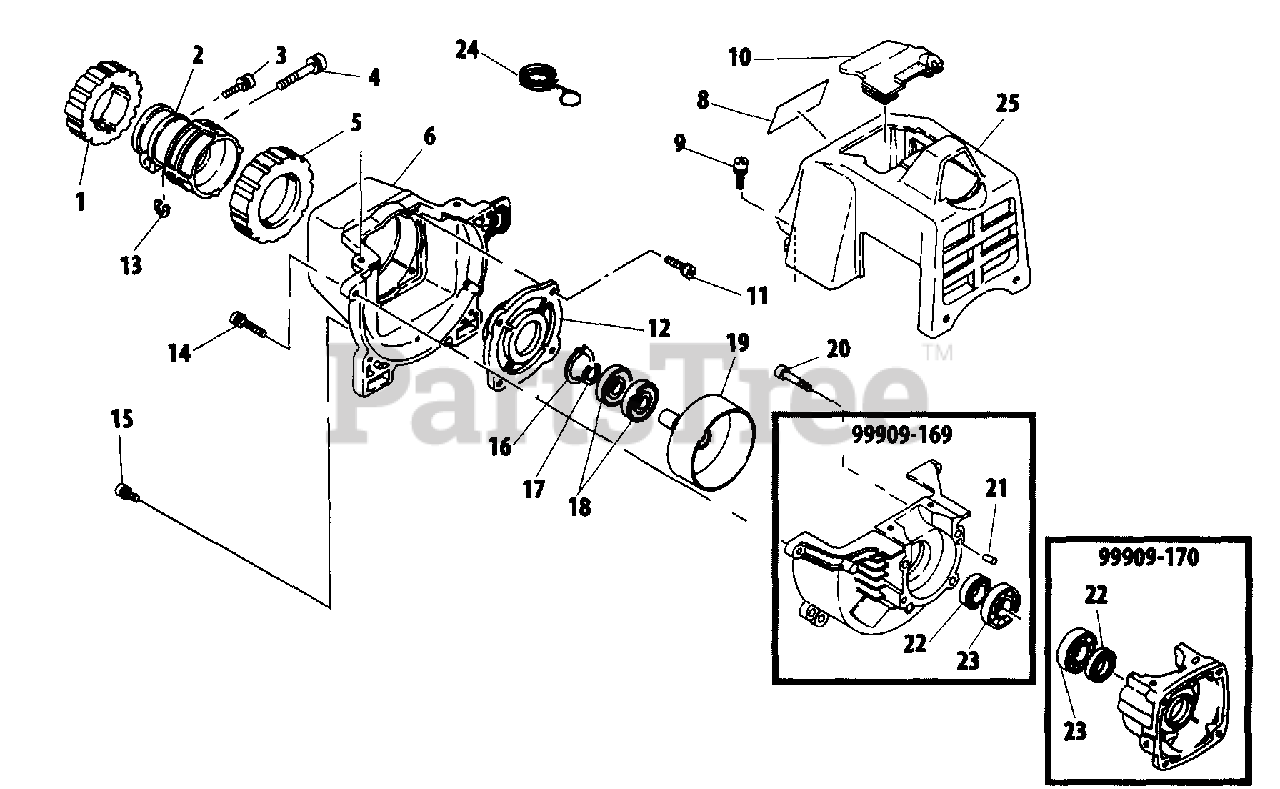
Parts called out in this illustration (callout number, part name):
1	CUSHION - FRONT
2	JOINT
3	SCREW - 5X65
4	SCREW - 6X28
5	CUSHION - REAR
6	CASE, FAN
8	LABEL - MODEL
9	SCREW - 5X16
10	COVER
11	SCREW - 5X16
12	CASE, CLUTCH
13	SHIM
14	SCREW - 5X18
15	SCREW - 5X20
16	RING, RETAINING - 28
17	RING, RETAINING
18	BEARING, BALL - 6001DDUC3
19	DRUM, CLUTCH
20	SCREW - 5X25
21	PIN - LOCATING
22	SEAL, OIL - 12
23	BEARING, BALL - 6201
24	GUIDE, CABLE
25	COVER, ENGINE
